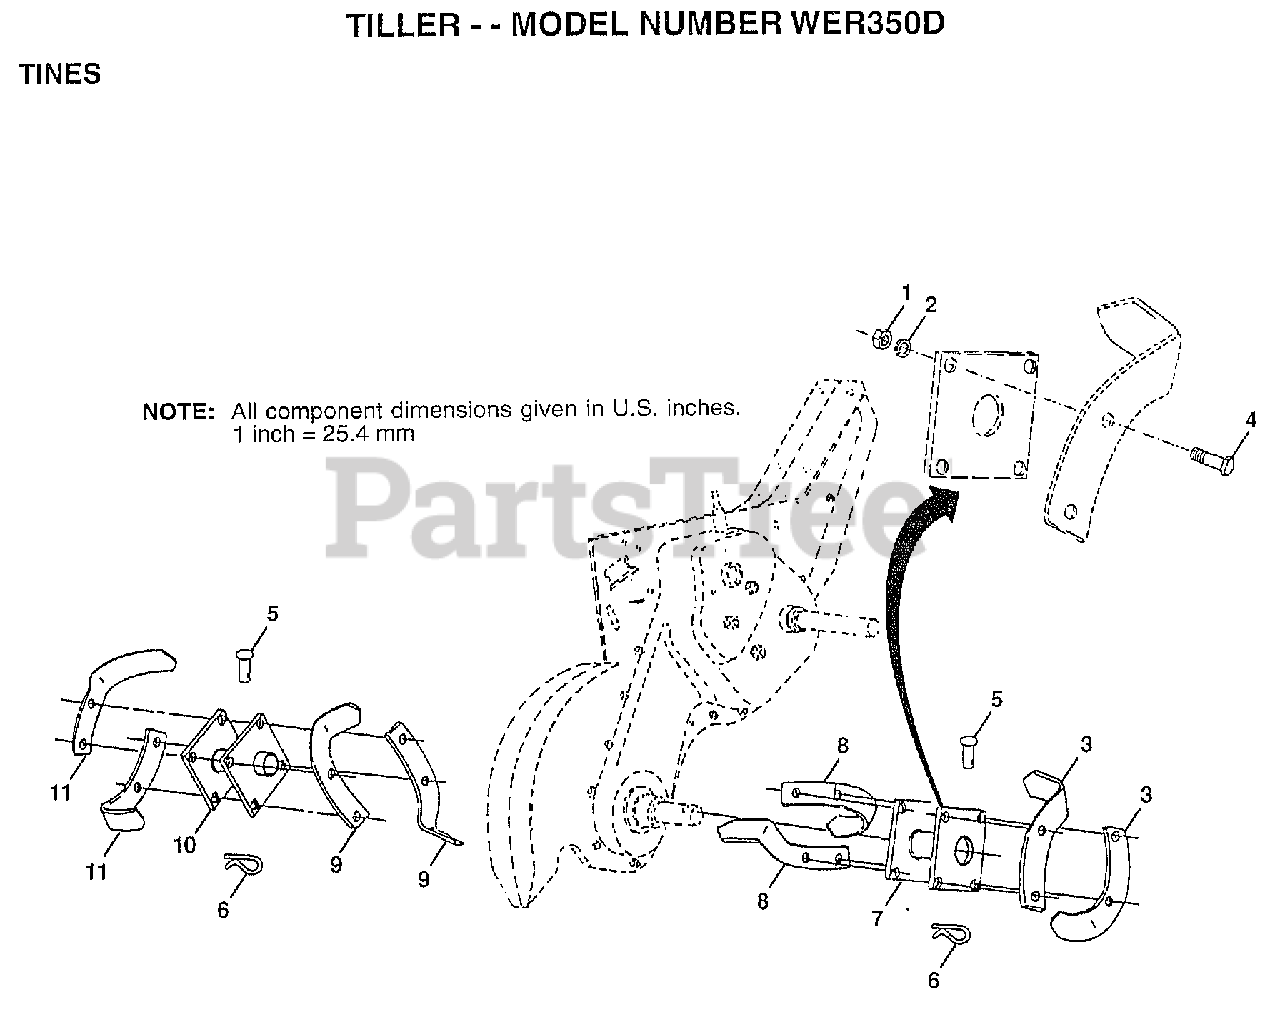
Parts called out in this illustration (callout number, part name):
1	Nut, Hex 3/8-24
2	Washer, Lock 3/8
3	Tine, Outer, R.H.
4	Bolt, Hex 3/8-24 x 1
5	Pin, Shear
6	Clip, Hairpin
7	Assembly, Hub and Plate, R.H.
8	Tine, Inner, R.H.
9	Tine, Inner, L.H.
10	Assembly, Hub and Plate, L.H.
11	Tine, Outer, L.H.
